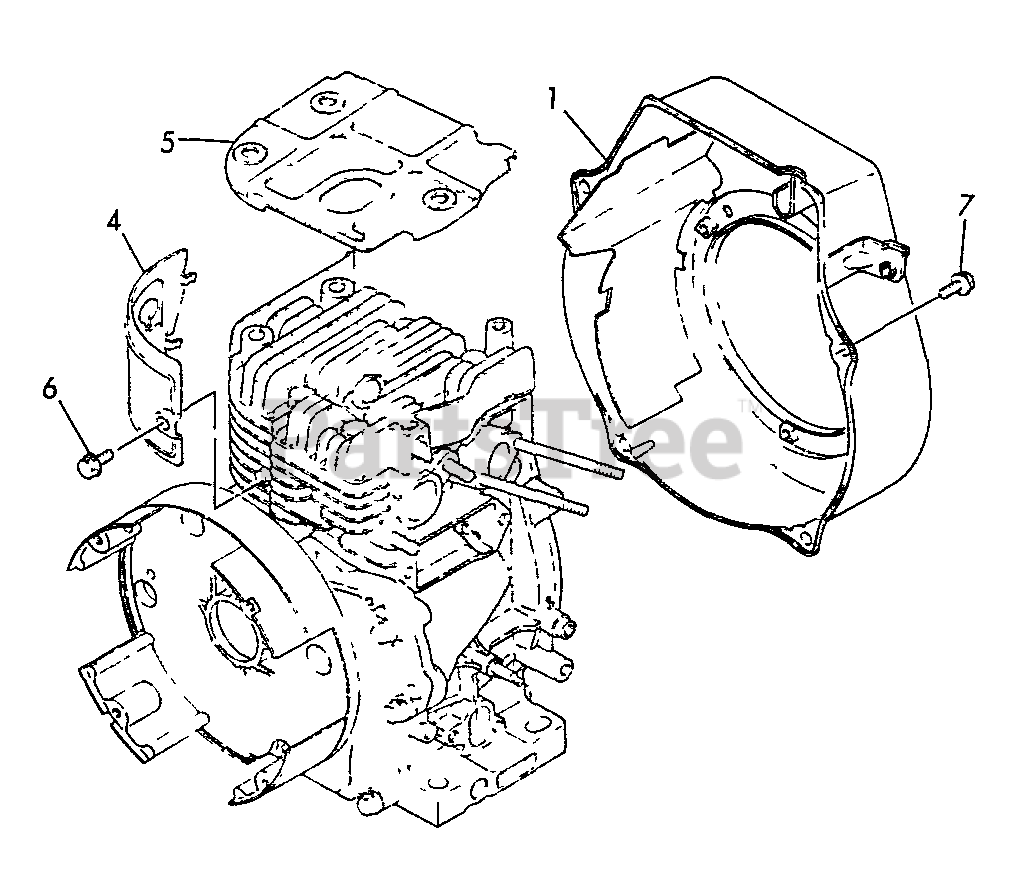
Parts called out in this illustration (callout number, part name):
1	CASE, FAN
4	PLATE
5	COVER, HEAD
6	BOLT - 6×8 -- PLATED
7	BOLT - 6×8 -- PLATED
